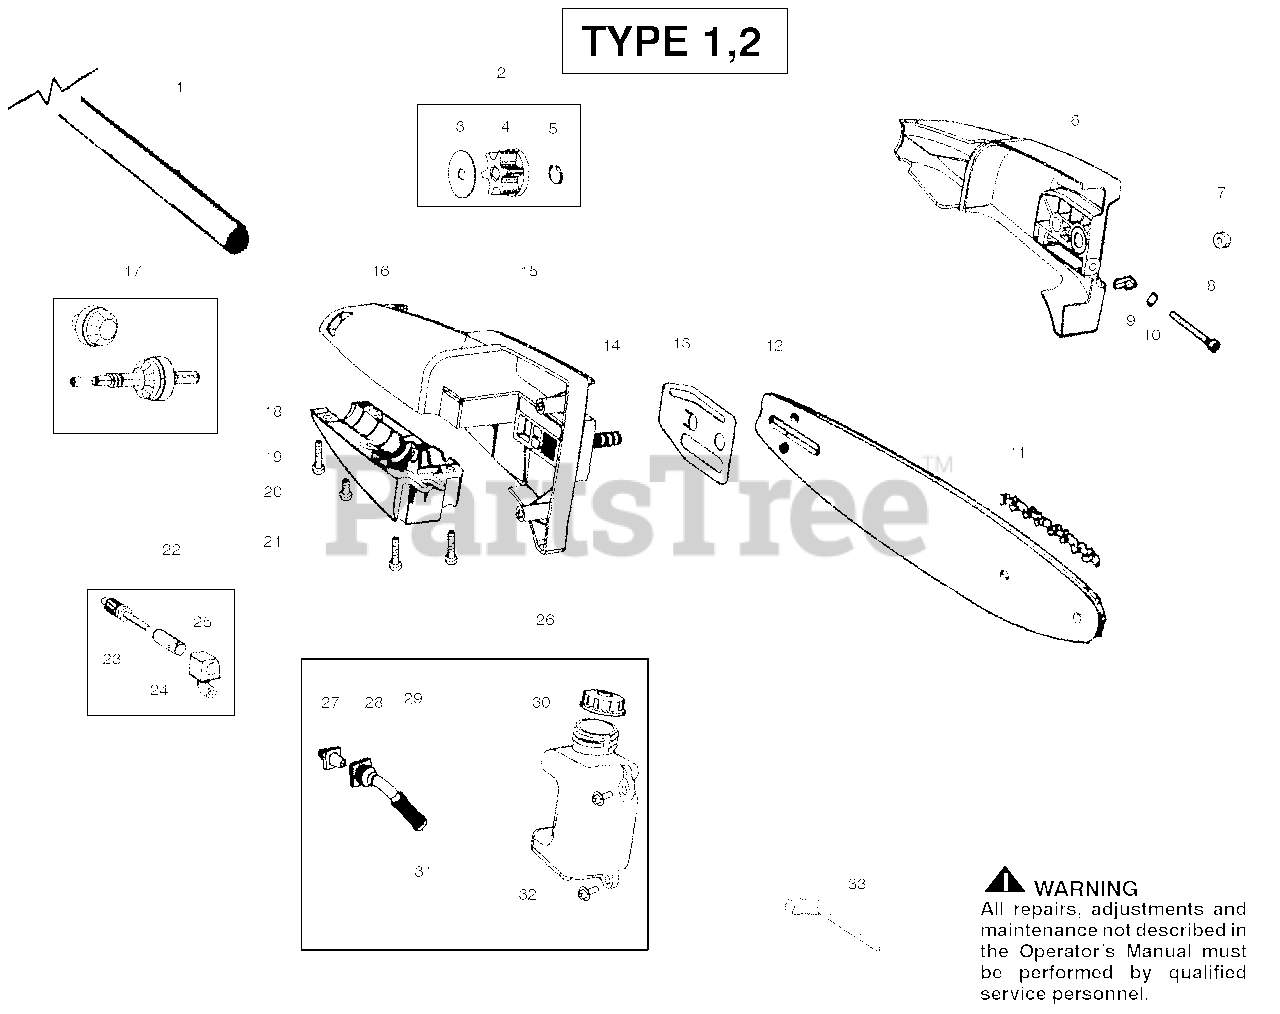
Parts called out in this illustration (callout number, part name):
1	Assy-Driveshaft
2	Kit-Sprocket Assy.
5	Retainer-Sprocket
6	Assy-Bar Clamp
7	Nut-Bar Mounting
8	Kit-Bar Adjust
9	Pin-Bar Adjust
10	Retainer-Bar Adjust
11	Accy.-Chain-8"
13	Plate-Bar pad
15	Hsg.-Upper
17	Kit-Gear Assy
20	Screw-Align
22	Kit-Oil Assy
23	Assy-Gear Plunger
26	Assy-Oil Tank
27	Fitting-Oil Line
28	Intake-Oil Line
29	Filter-Oil
30	Cap-Oil
31	Plug-Oil Filter
